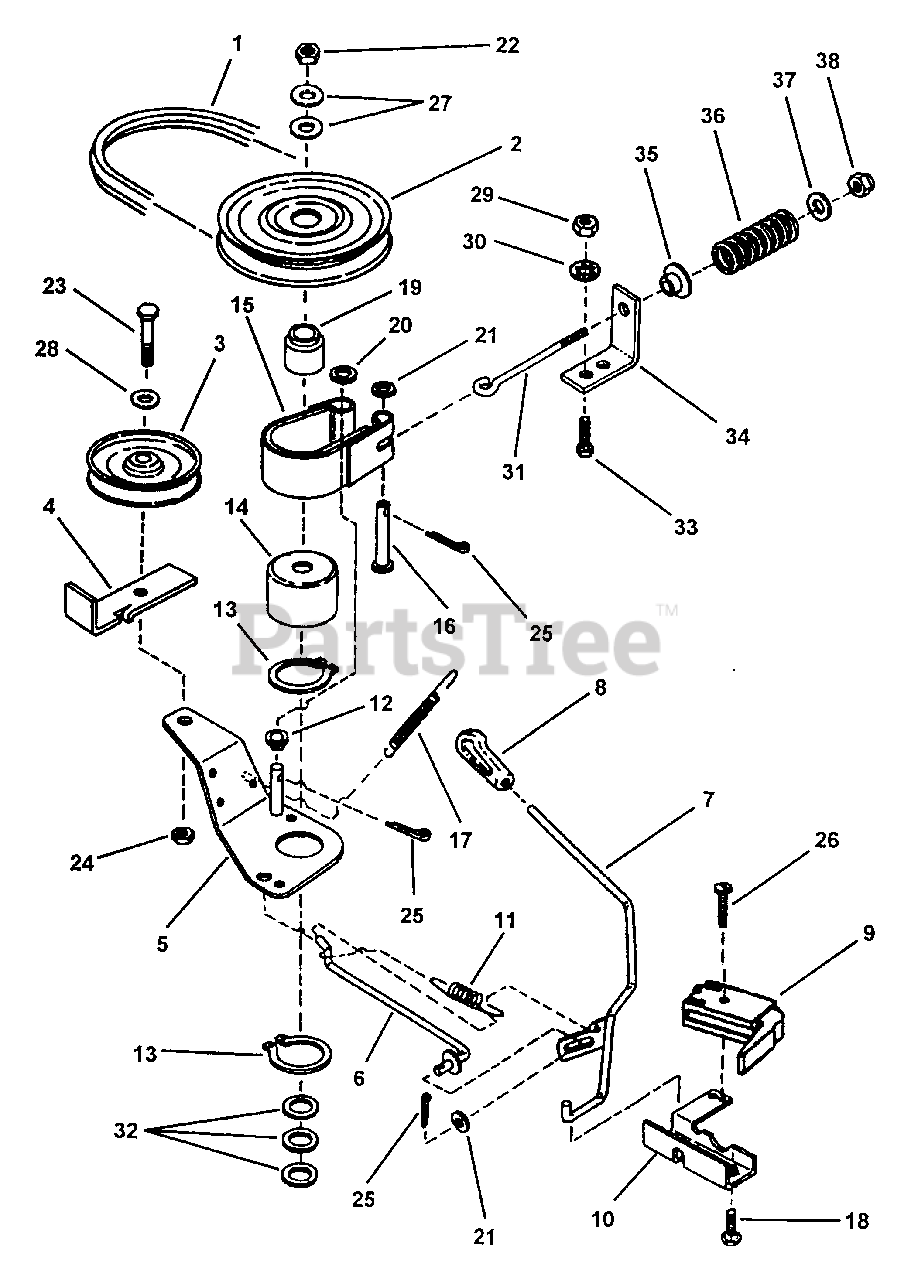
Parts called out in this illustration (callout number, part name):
1	BELT, Drive (72.25" AA Section)
2	PULLEY, Spindle
3	PULLEY, Idler (4" O.D., .375" I.D.)
4	RESTRICTOR, Belt
5	WELDMENT, Idler Arm
6	ROD, Idler
7	HANDLE, Blade Lever(On-Off)
8	GRIP, Handle
9	SWITCH, Deck Interlock
10	MOUNT, Blade Lever and Switch
11	SPRING, Blade Handle
12	SPACER
13	RING, 2" External Retaining
14	DRUM, Brake
15	BAND, Brake
16	PIN, 1/4 x 1-5/8" Clevis
17	SPRING
18	SCREW, 1/4-20 x 5/8"Hex Washer Self-Tap
19	HUB, Pulley
20	WASHER, 3/8" Flat
21	WASHER, 1/4" Flat
22	NUT, 3/4-16 Hex Jam
23	SCREW, 3/8-16 x 1-1/2" Hex Head Cap, Grade 5
24	NUT, 3/8-16 Hex Nyloc
25	PIN, 3/32 x 3/4" Cotter
26	SCREW, #10-32 x 1" Hex Washer Self-Tap
27	WASHER, 49/64 x 1-1/2" Flat
28	WASHER, 3/8" Flat
29	NUT, 5/16-24 Hex
30	WASHER, 5/16" Lock
31	EYEBOLT, 1/4-20 x 4"
32	WASHER, 3/4" Flat
33	SCREW, 5/16-24 X 3/4" Hex Head Cap, Grade 5
34	ANCHOR
35	BUSHING
36	SPRING
37	WASHER, 9/32" Flat
38	NUT, 1/4-20 Hex Top Lock
